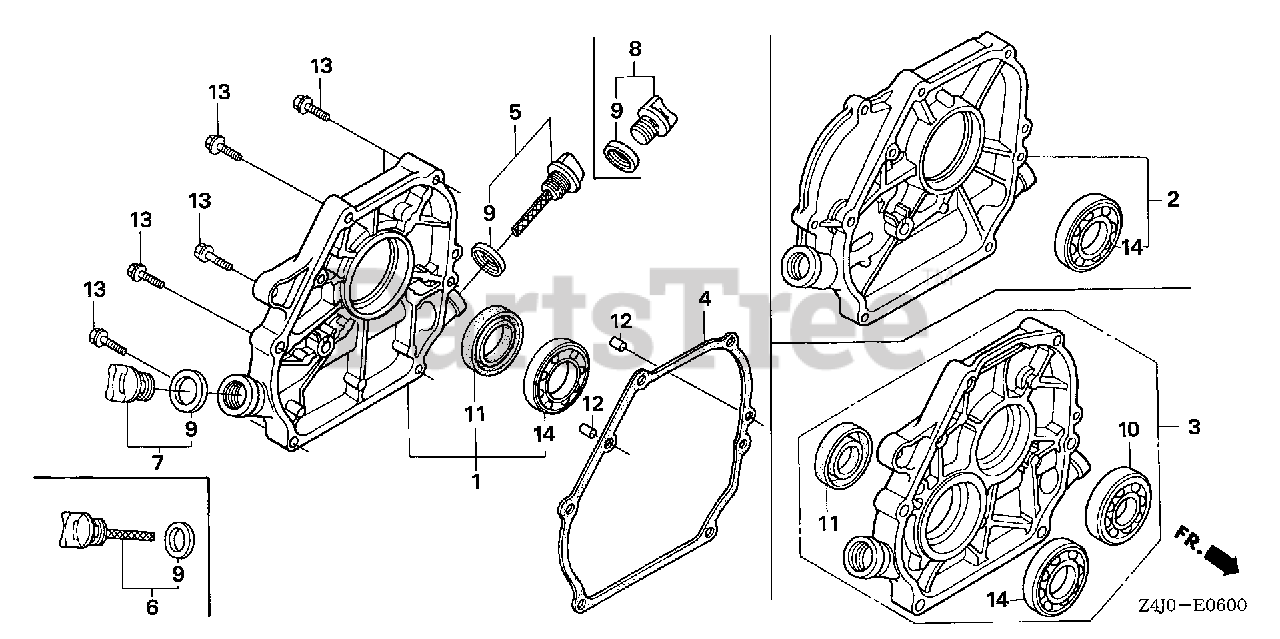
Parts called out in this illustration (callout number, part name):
1	COVER ASSY., CRANKCASE
4	GASKET, CASE COVER (NON-ASBESTOS)
5	CAP ASSY., OIL FILLER (GRAY)
7	CAP ASSY., OIL FILLER
9	GASKET, OIL FILLER CAP
11	OIL SEAL (25X41X6) (NOK)
12	PIN, DOWEL (8X14)
13	BOLT, FLANGE (8X32)
14	BEARING, RADIAL BALL (6205)
